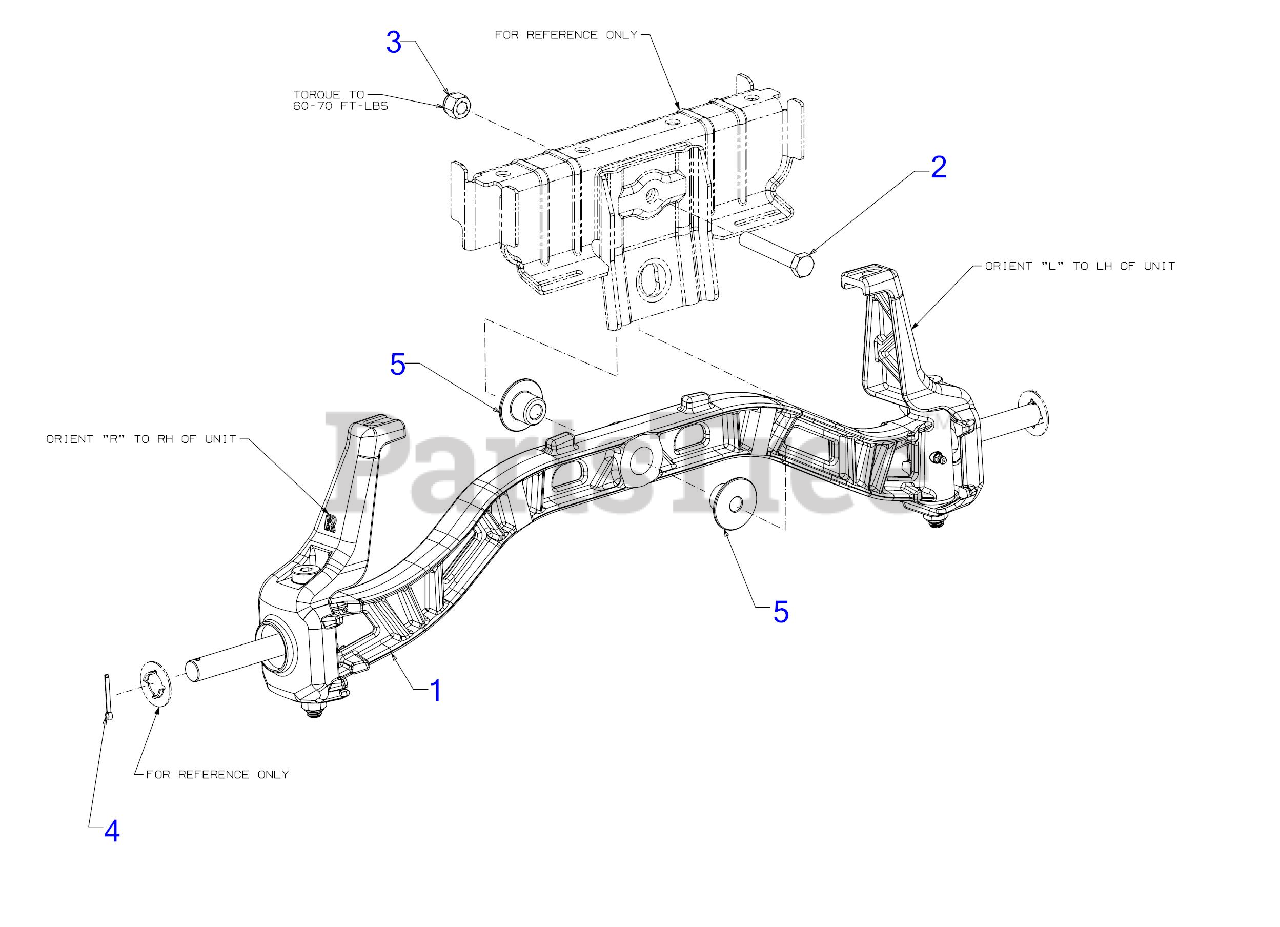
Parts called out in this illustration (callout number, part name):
1	FRONT AXLE ASSEMBLY
2	HEX SCREW 1/2-13 x 3.00
3	HEX LOCK NUT NYLON
4	COTTER PIN-5/32 DIA
5	SHOULDER SPACER
